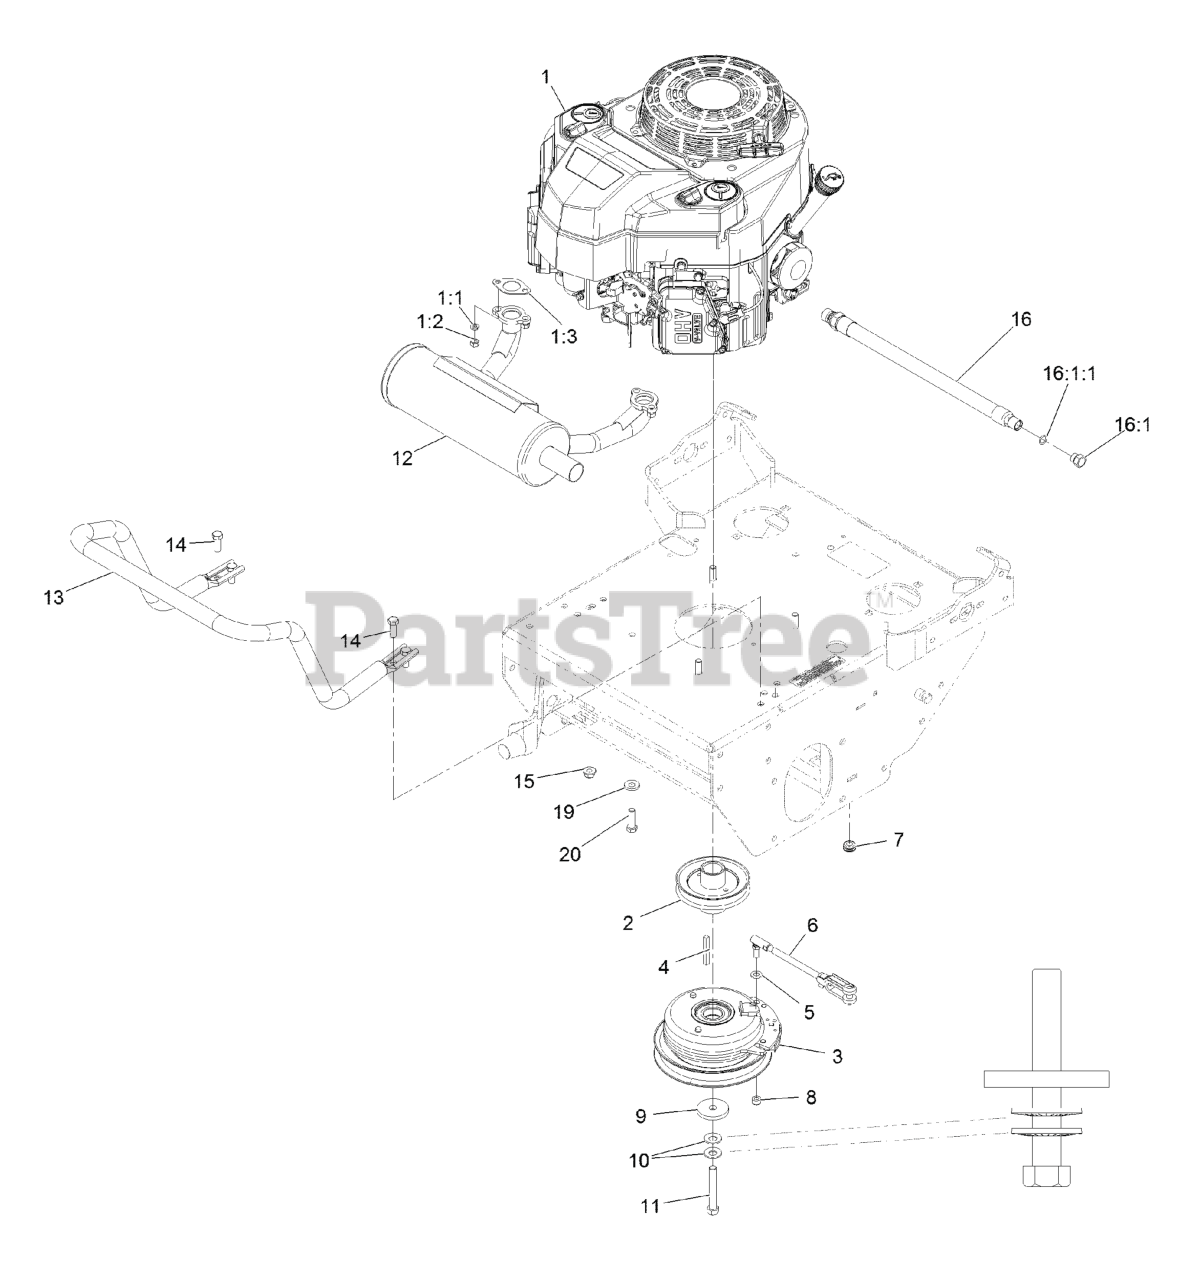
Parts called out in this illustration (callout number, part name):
1:1	WASHER-LOCK
1:3	GASKET-EXHAUST
2	SHEAVE, W/ HUB
3	CLUTCH, 105 FT/LBS, 1.13
4	KEY-SQUARE
5	WASHER-PLAIN
6	ASM, CLUTCH ANCHOR
7	GROMMET
8	NUT-LOCK
9	WASHER-CLUTCH
10	WASHER-SPRING
11	SCREW-HH
12	MUFFLER-HORIZONTAL
13	GUARD-MUFFLER
14	SCREW-HH
15	NUT-HF, NI
16	ASM, ENGINE OIL DRAIN HOS
16:1	PLUG-HH
16:1:1	O-RING
19	WASHER-BELLEVILLE
20	SCREW-HH
